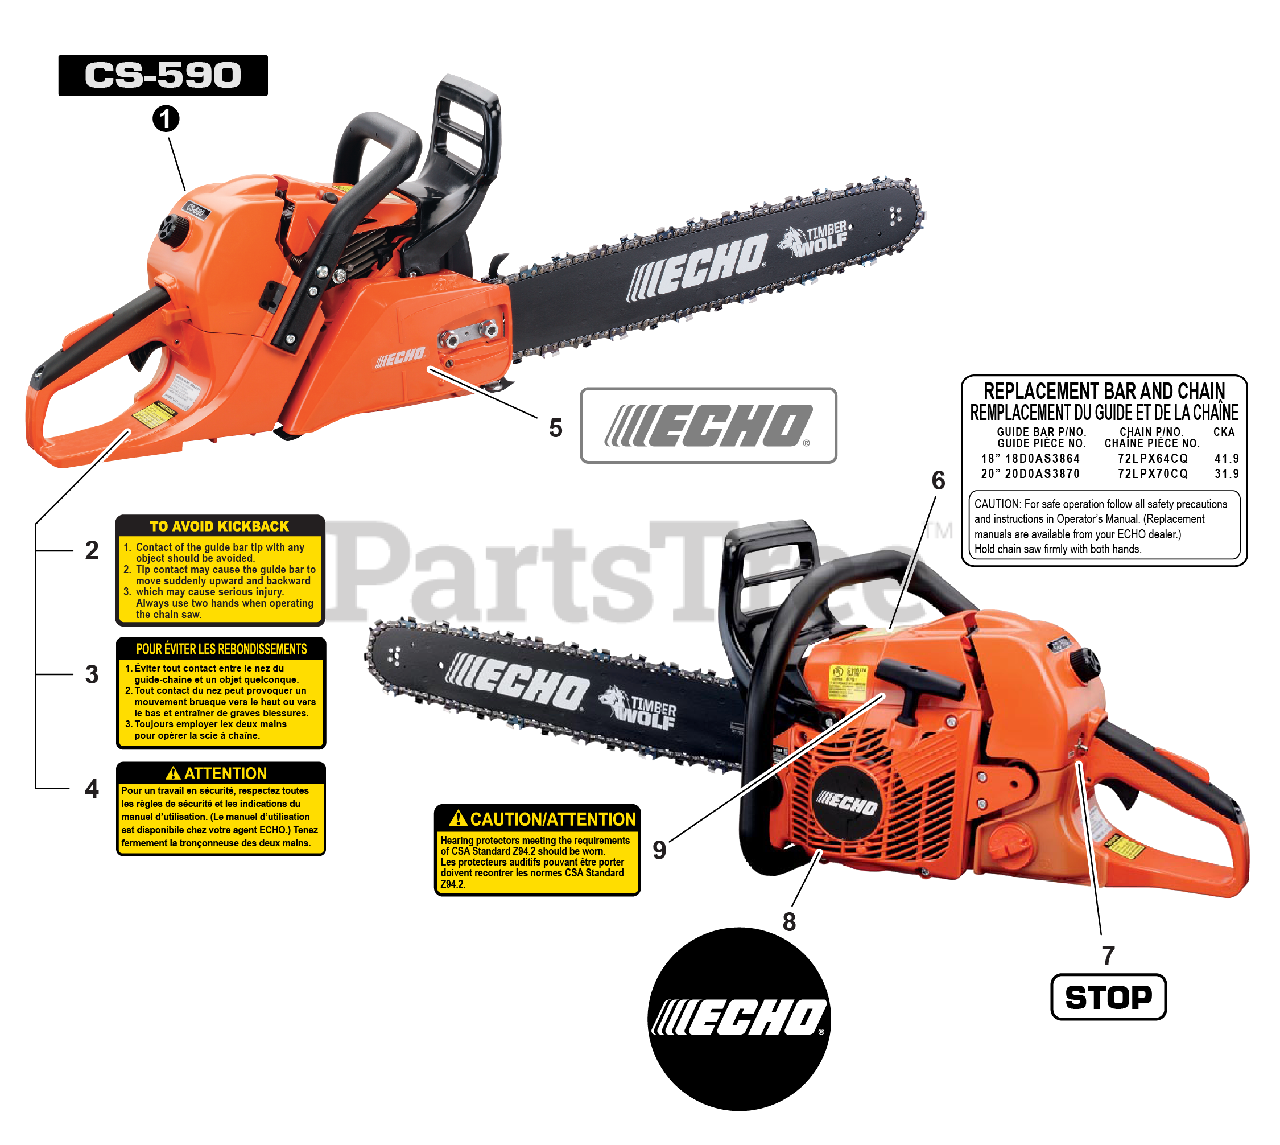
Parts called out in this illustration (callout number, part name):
1	LABEL - MODEL -- CS-590
2	LABEL - KICKBACK
3	LABEL - KICKBACK
4	LABEL - ATTENTION
5	LABEL - ECHO
6	LABEL - BAR & CHAIN
7	LABEL - STOP
8	LABEL - ECHO
9	LABEL - NOISE
